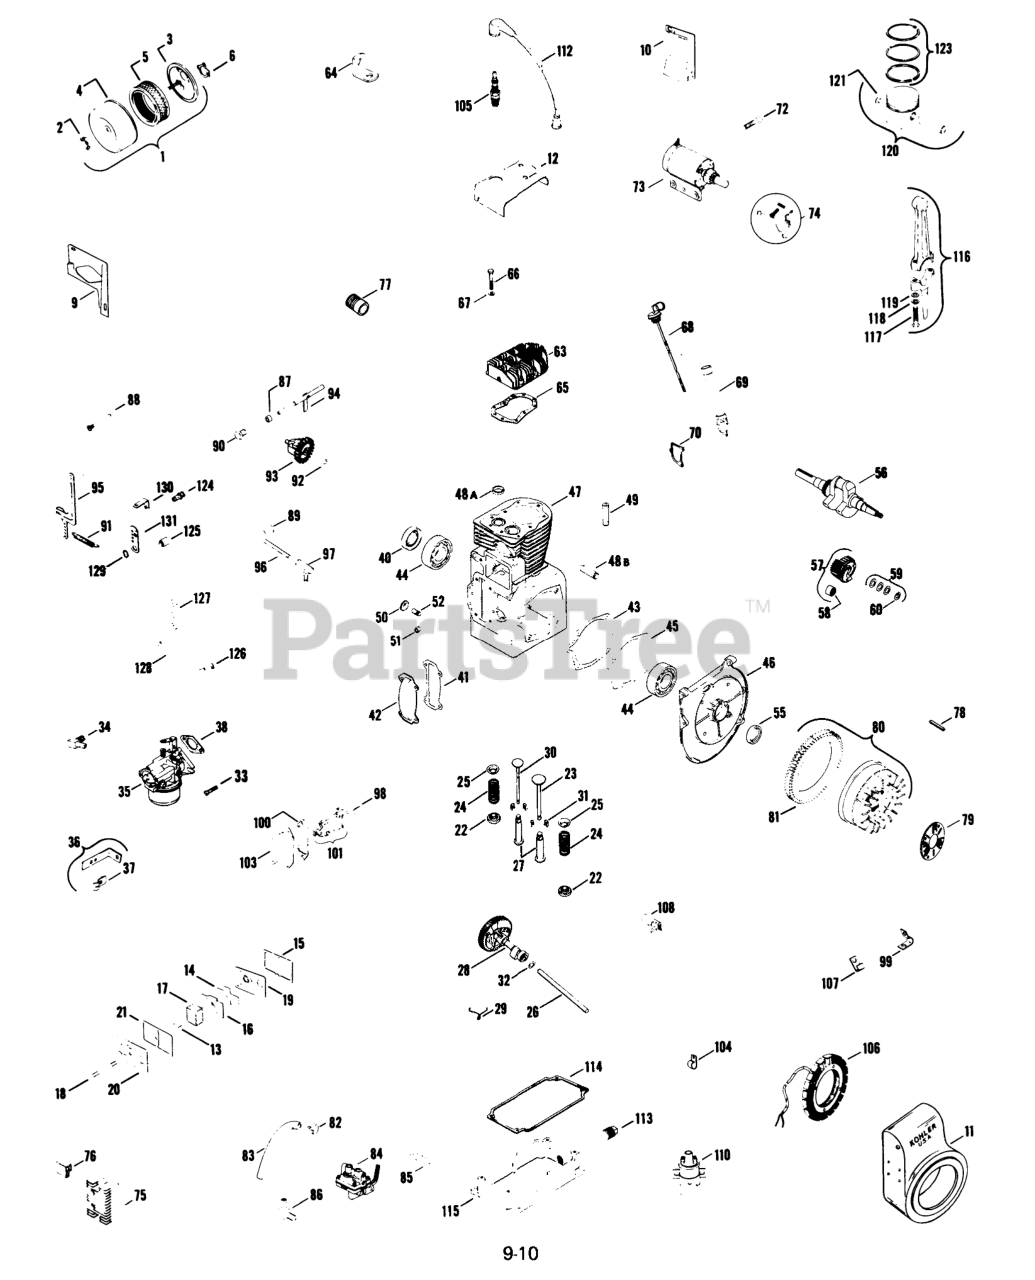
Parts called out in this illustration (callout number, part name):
1	Cleaner-Air Assembly
2	Nut-Wing
3	Base-Air Cleaner
4	Cover-Air Cleaner
5	Element
6	Gasket-Air Horn
9	BaffLe side air
10	Baffle cylinder
11	Housing-Blower
12	Baffle-Head
13	Seal
14	Reed
15	Gasket
16	Baffle breather
17	Filter Breather
18	Stud, valve cover
19	Plate
20	Cover valve
21	Gasket
22	Retainer-Spring
23	Valve-Intake
24	Spring
25	Retainer-Spring
26	Pin (Service)
27	Tappet
28	Camshaft-assembly
29	Spring-Actuating
30	Valve, exhaust
31	Keeper, Valve
32	Spacer
33	Screw sitd. hd.
34	Elbow
35	Carburetor-assembly
36	Bracket, choke
37	Clip
38	Gasket
40	Seal rear oil
41	Gasket
42	Cover
43	Gasket
44	Ball Bearing
45	Gasket
46	Plate Bearing
47	Block, cylinder - assembly (Use B-237416 Miniblock)
48A	Insert
48B	Shaft
49	Guide Valve
50	Plug
51	Bearing
52	Shaft-Govemor
55	Seal, Front OiI
56	Crankshaft
57	Gear
58	Bearing,needle
59	Kit-Spacer
60	Retainer
63	Belt Guide
64	Lift Cable
65	Gasket-Head
66	Screw
66	Screw-H.C.
67	Washer
68	Dipstick
69	Tube, fill
70	Gasket
72	Screw
73	Starter
74	Kit, Brush & Spring
75	Regulator
76	Connector
77	Nipple
78	Key
79	Screen grass
80	Flywheel-Assembly
81	Gear Ring
82	Clamp
83	Line Fuel
84	Pump, fuel
85	Gasket, pump
86	Elbow
87	Spacer
88	Screen-Oil Filter
89	Retainer, rod
90	35210A GILSON SNWTH
91	Tube-Breather
92	Washer
93	Gear, Governor
94	Shaft, Governor
95	Lever, Governor
96	Rod ball joint
97	Ball Joint
98	Rod, breaker
99	Clip
100	Gasket, Cover
101	Breaker
103	Cover breaker
104	Clip
105	Plug, spark
106	Stator
107	Clip
108	Condenser
110	Coil
112	Kit, Hi-Tension
113	Plug
114	Gasket
115	Base, oil pan
116	Rod, Connecting
117	Screw, connecting rod
118	Washer
119	Washer
120	Piston - assembly (Std.) (Includes pin & retainers)
121	Pin, Retainer
123	Ring set-Std. & .003 (Svc.)
124	Clamp, swivel wire
125	Spacer
126	Retainer Rod
127	Bellcrank
128	Rod, throttle
129	Washer
130	Spacer
131	Bracket
